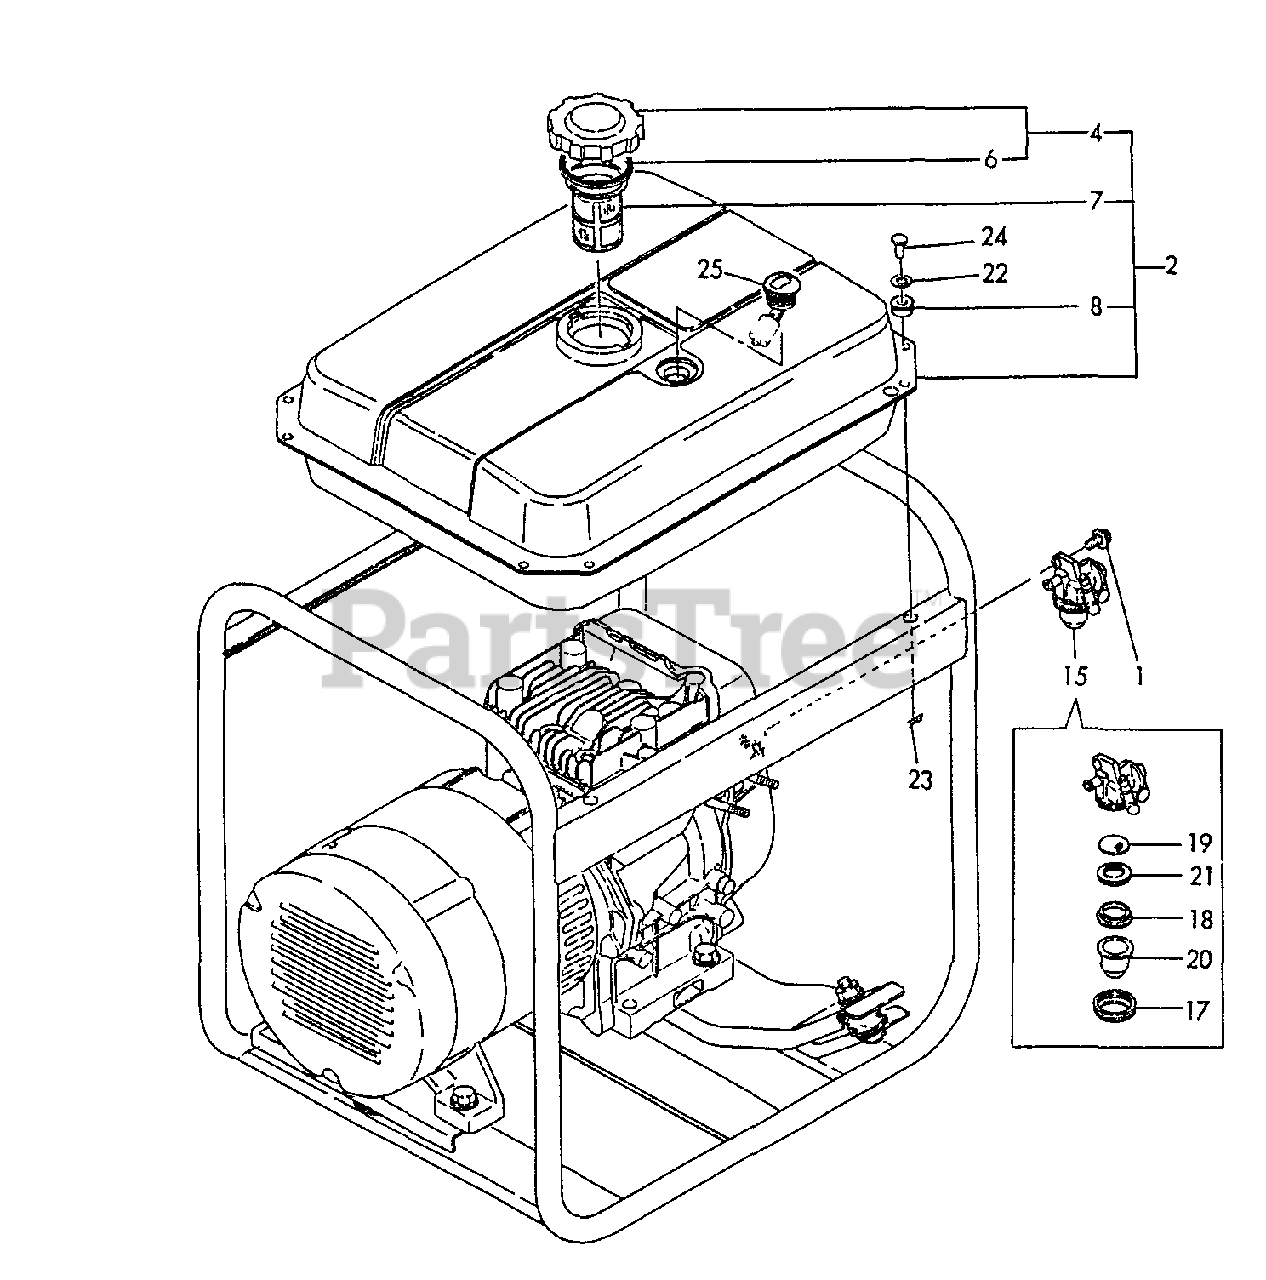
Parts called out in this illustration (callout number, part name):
1	BOLT - 6X8 -- PLATED
2	FUEL TANK ASSY
4	CAP ASSY
6	GASKET
7	STRAINER, FUEL
8	GROMMET
15	FUEL COCK ASSY
17	RETAINER
18	GASKET
19	FILTER, FUEL
20	BOWL, STRAINER
21	PLATE
22	WASHER
23	PIN - 6 -- SNAP
24	PIN - 6X14
25	GAUGE, FUEL
